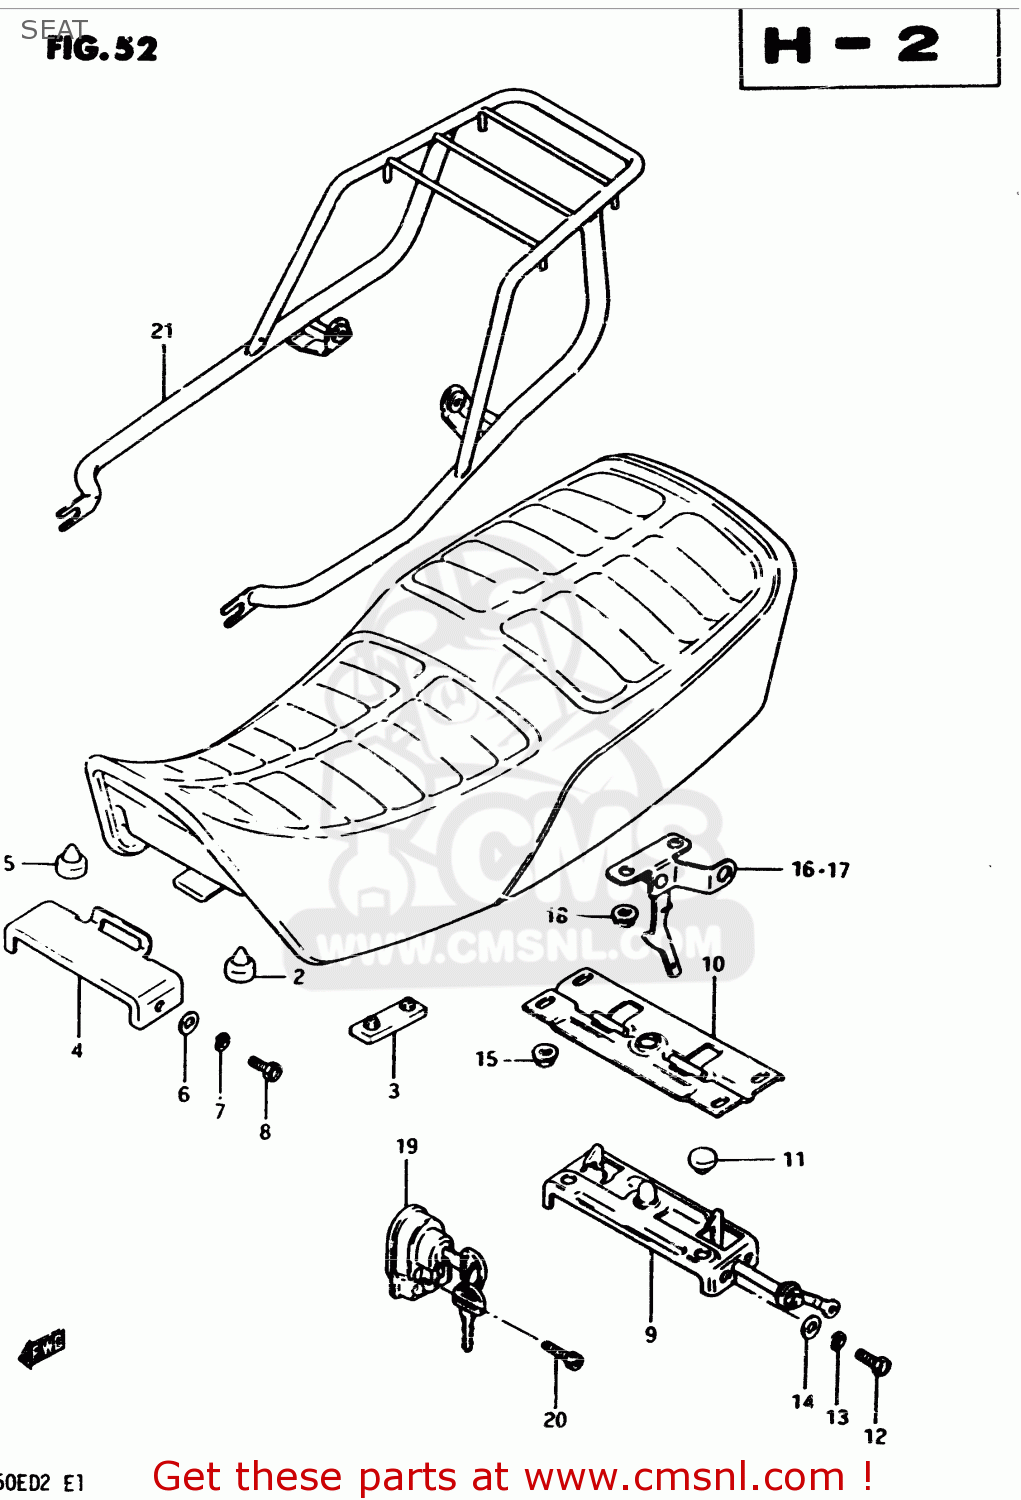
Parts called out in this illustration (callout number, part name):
1	SEAT ASSY (BLACK)
2	CUSHION
3	CUSHION
4	PLATE,SEAT LOCK,FRONT
5	CUSHION(11.5X22X20)
6	WASHER
7	LOCK WASHER
8	BOLT
9	PLATE,CLAMP GUIDE
10	PLATE,SEAT CLAMP GUIDE
11	CUSHION
12	SCREW
13	LOCK WASHER
14	WASHER
15	NUT
16	LEVER,SEAT HOOK,RIGHT
17	LEVER,SEAT HOOK,LEFT
18	NUT
19	LOCK ASSY,HELMET
20	BOLT 5X25
21	CARRIER
